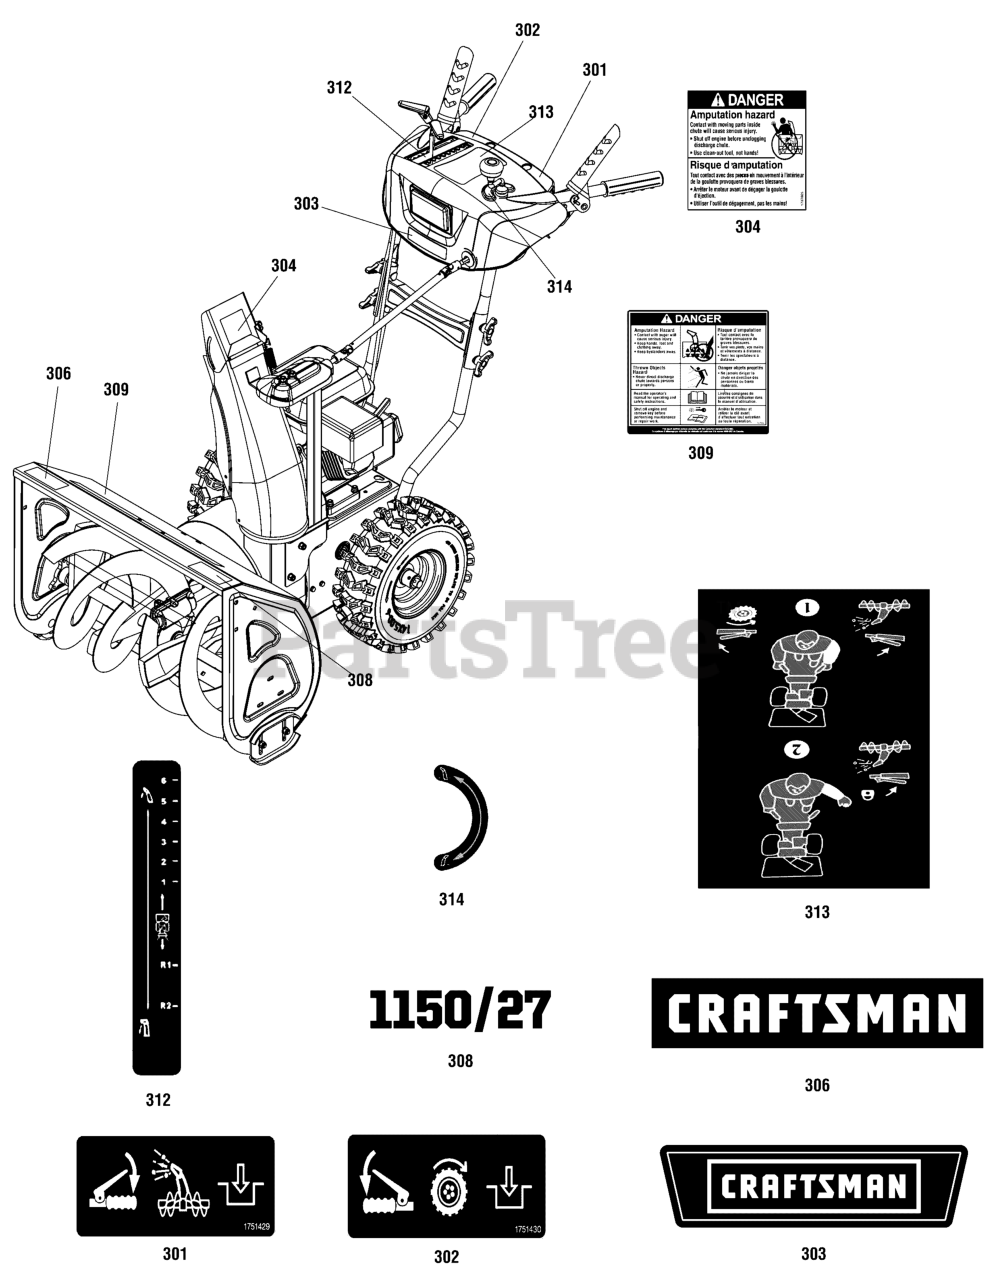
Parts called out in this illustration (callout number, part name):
1	KIT-DECAL, Craftsman 1150/27
301	DECAL, Auger Control
302	DECAL, Traction Control
303	*DECAL, Control Panel, Craftsman
304	DECAL, Danger Chute
306	*DECAL, Craftsman Logo
309	DECAL, Danger Foot
312	DECAL, 1-6 Transmission Speed Control
313	*DECAL, Free Hand Operation
314	DECAL, Chute Rotation
